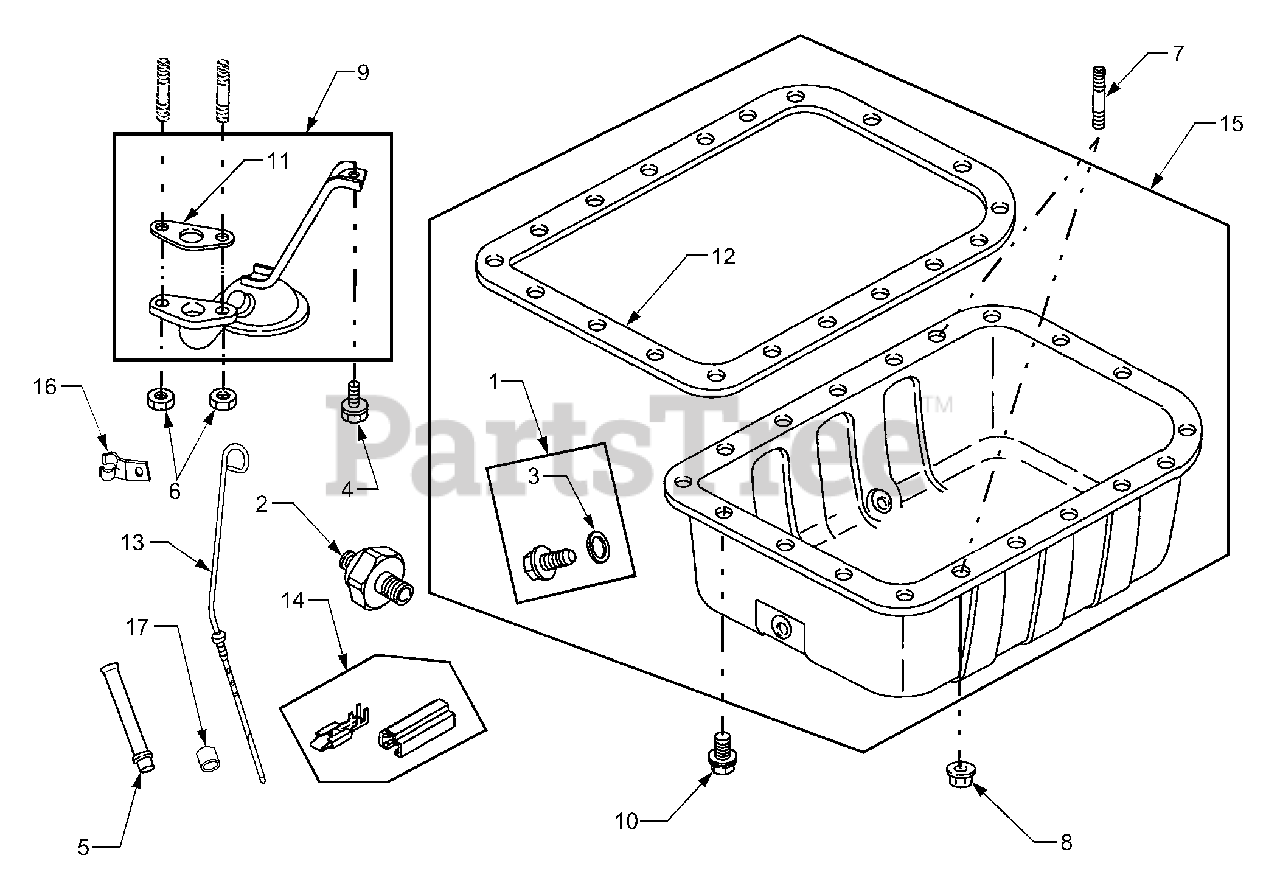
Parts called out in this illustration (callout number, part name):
1	Plug, Oil Drain 16mm
2	Switch, Oil Pressure
3	Washer, Sealing
4	Screw, Oil Pump Screen
5	Tube, Dipstick
6	Nut, Oil Pump Screen
7	Stud, Oil Pan
8	Nut, Oil Pan
9	Oil Pump Screen
10	Screw, Oil Pan
11	Gasket, Oil Pump Screen
12	Gasket, Oil Pan
14	Connector, Oil Pressure Switch
15	Pan, Oil
16	Bracket, Support
17	Collar, Dipstick Tube
